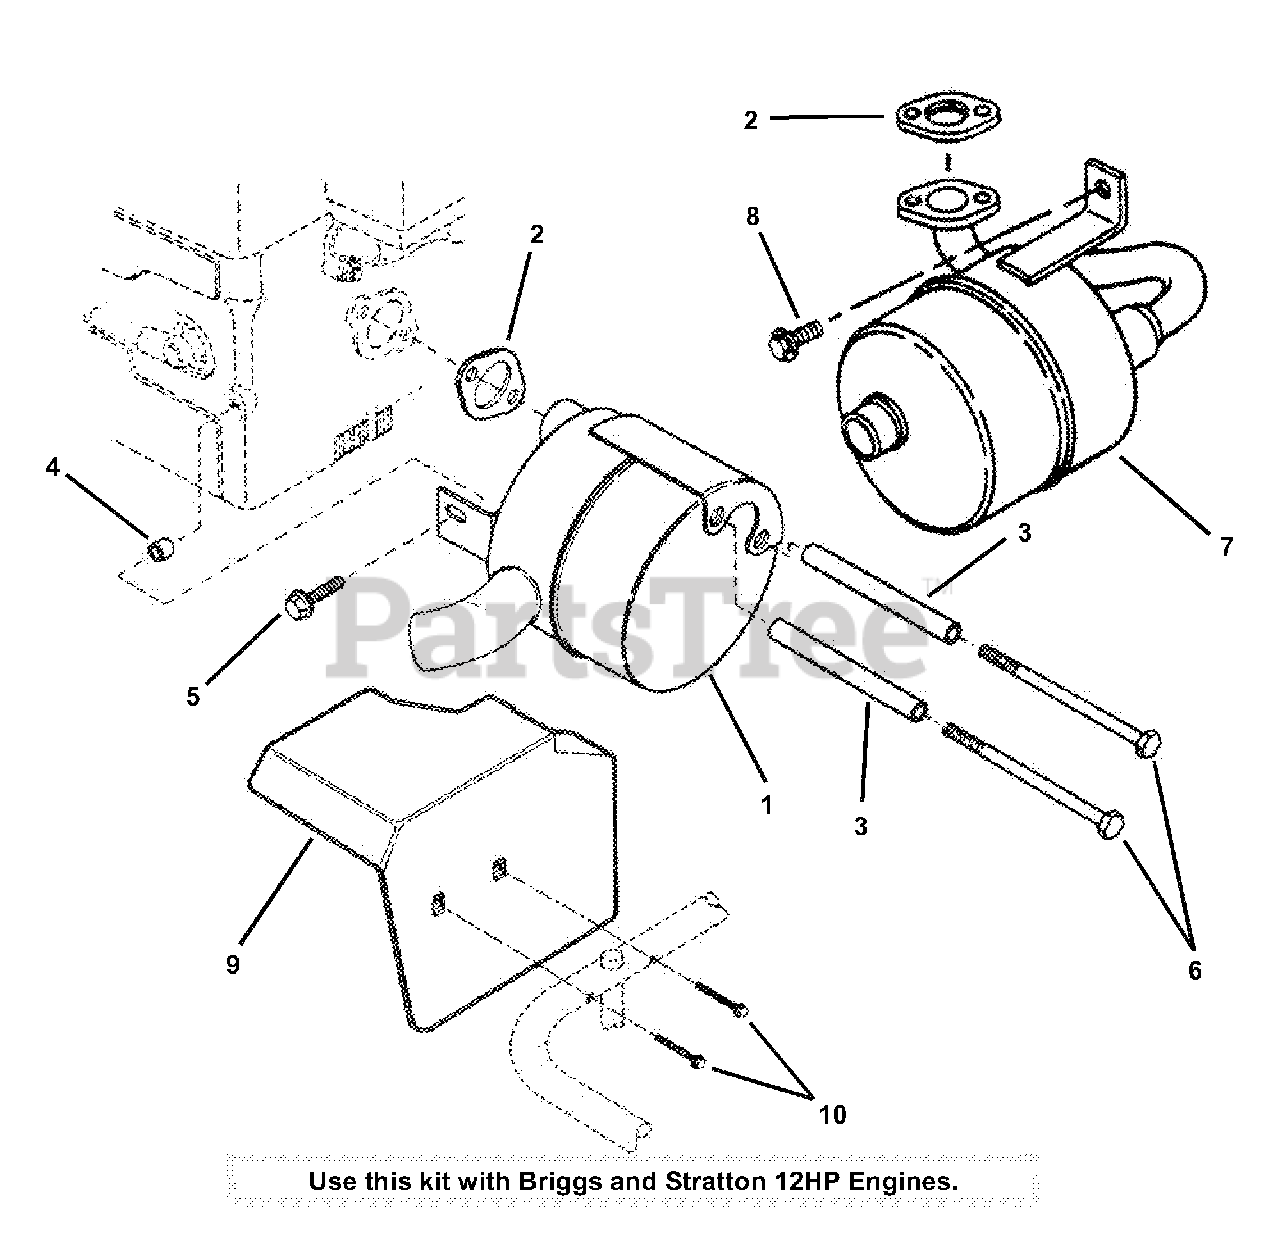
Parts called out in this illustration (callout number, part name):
1	MUFFLER, 12HP Briggs
2	GASKET, Exhaust
3	SPACER, .312 I.D. x 3-1/2"
4	SPACER, .33 x .5 x .40 Thick
5	BOLT, 1/4-20 x 1" Hex Flange Lock
6	SCREW, 5/16-18 x 4-1/4" Hex Head Cap
8	SCREW, 1/4-20 x 5/8" Hex Washer Self-Tapping
9	ASSEMBLY, Heat Shield
10	SCREW, #10-32 x 1-1/2" Hex Washer Head
